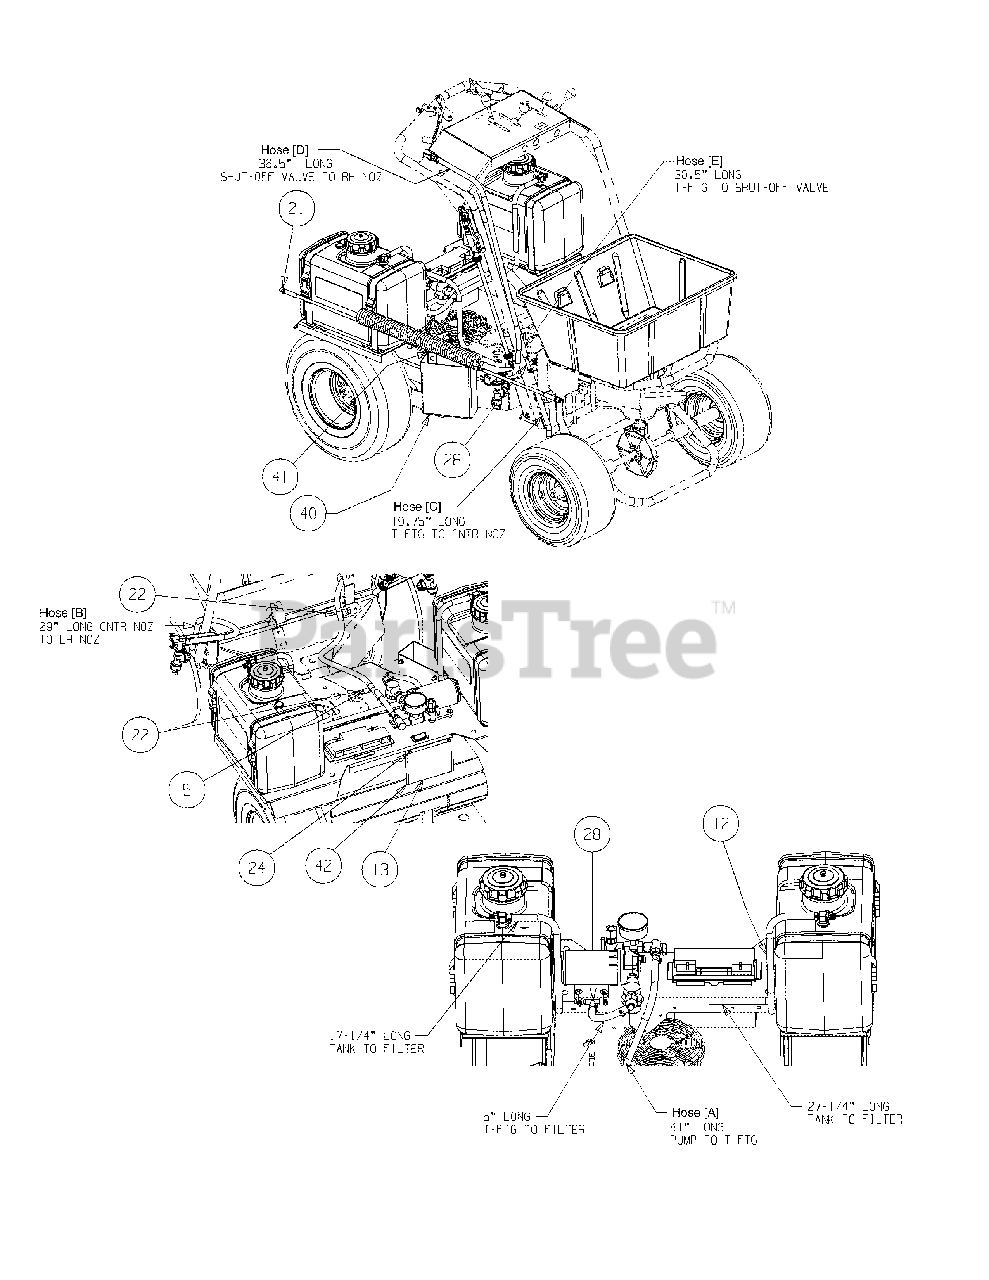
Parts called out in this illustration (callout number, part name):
5	Washer, 1/4
12	Hose, 3/8 x 17.20ft - 300psi
13	Decal, Safety Procedures
21	Hose Assembly, 25ft blue
24	Self Tapping Screw, #10-24 x 0.500
28	Tee Fitting, 3/8 Multi Barb
42	Bracket, Label
